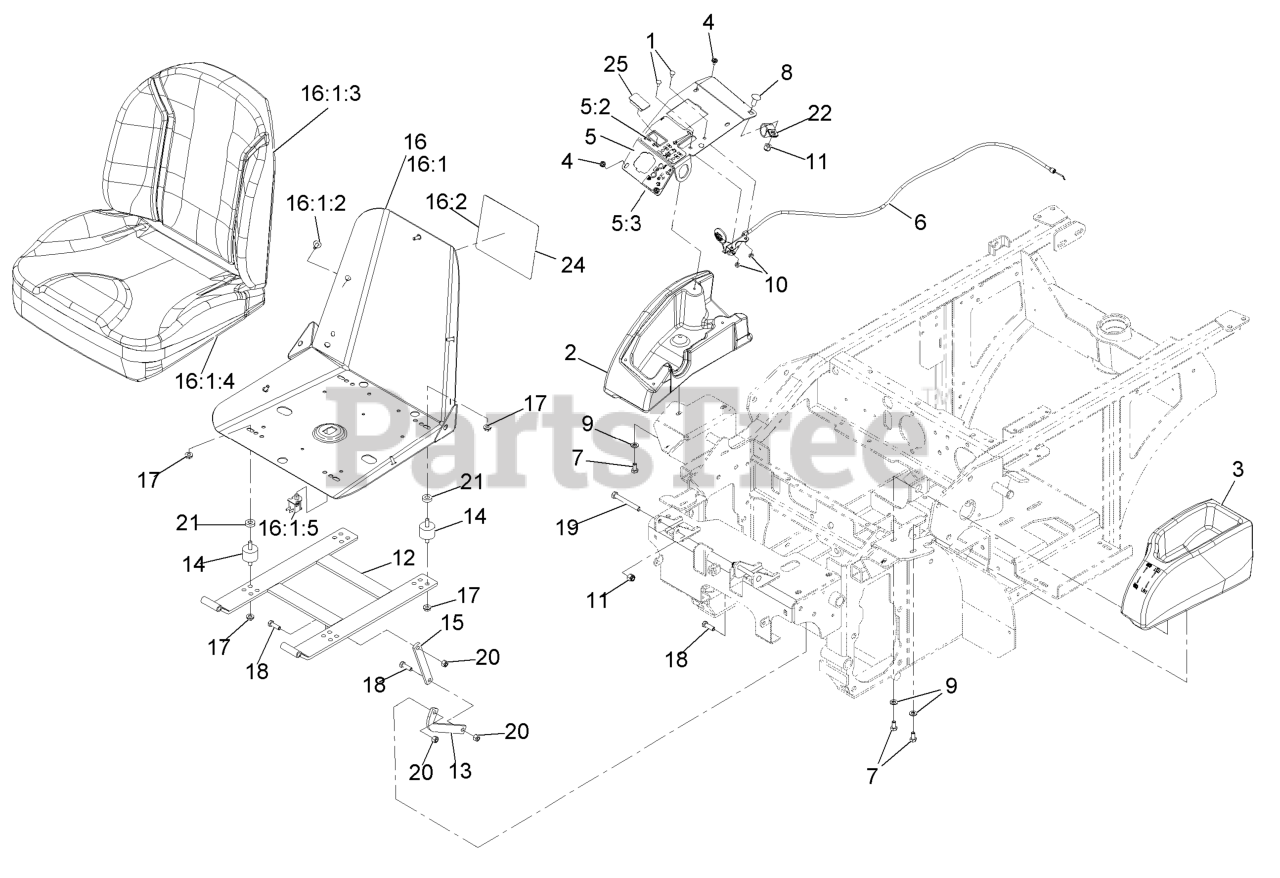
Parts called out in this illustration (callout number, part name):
1	BOLT-CARR
2	CONSOLE-RH
3	CONSOLE, LH GREY
4	SCREW-PPH
5	CONTROL PANEL ASM
5:2	Decal-Console
5:3	DECAL-SPEED CONTROL
6	CABLE-THROTTLE
7	SCREW-HH
8	SCREW-CARR
9	WASHER-PLAIN
10	NUT-LOCK, NI
11	NUT-LOCK, NI
12	FRAME-SEAT
13	LINK-SEAT STOP
14	MOUNT-VIBRATION, RUBBER
15	LINK-SEAT
16	ASM-SEAT W/DECAL
16:1	ASM-Seat, Navigator
16:1:2	BOLT-SEAT
16:1:3	CUSHION-SEAT, BACK
16:1:4	COVER-SEAT BOTTOM SVC
16:1:5	SWITCH-BAIL
16:2	Decal-Service Aid
18	SCREW-HH
19	SCREW-HH
20	NUT-LOCK, NI
21	SPACER
22	CLIP-LOOM
24	Decal-Service Aid
25	PLUG-HOLE
